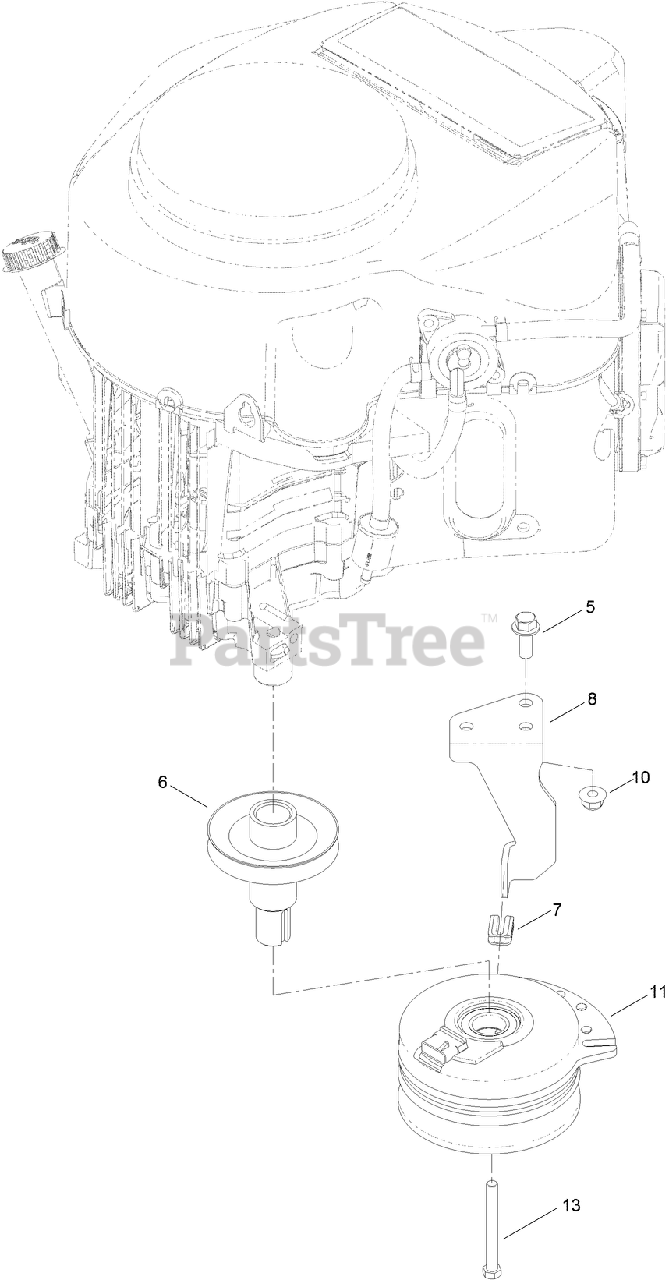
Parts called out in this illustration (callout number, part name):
5	SCREW-HHF
6	PULLEY-ENGINE
7	ISOLATOR-CLUTCH
8	STOP-CLUTCH (NARROW)
10	NUT-HF, NI
11	CLUTCH-ELECTRIC
13	SCREW-HH
